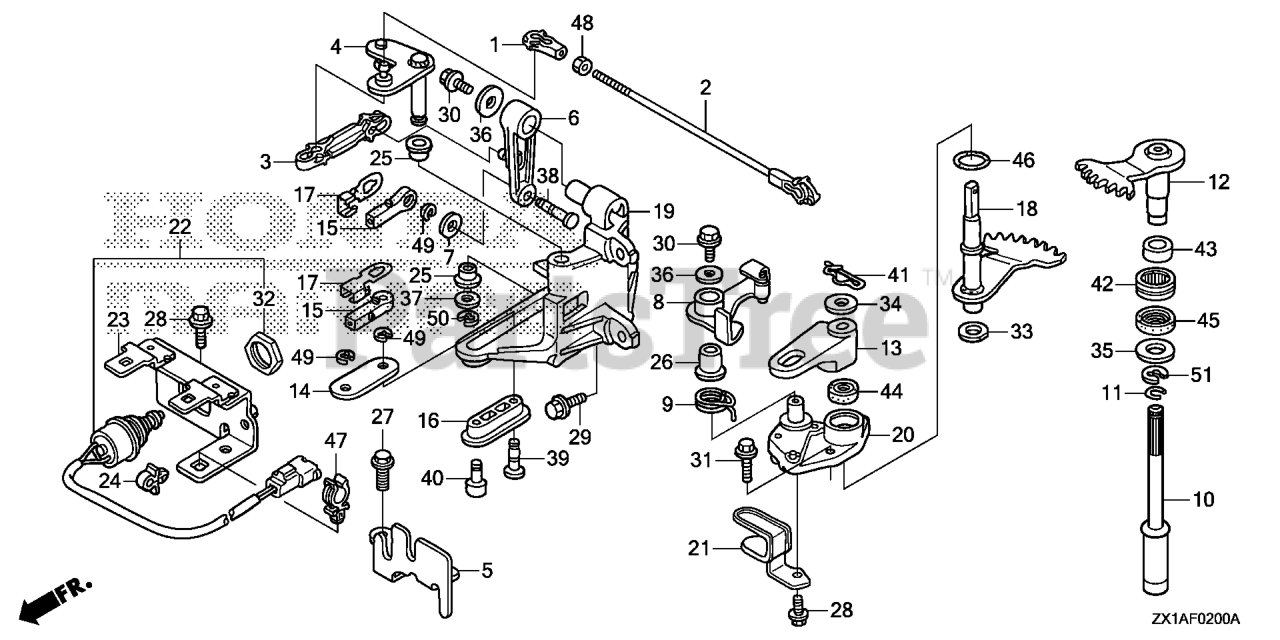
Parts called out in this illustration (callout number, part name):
1	LINKAGE, PIVOT
2	ROD, THROTTLE
3	LINK, THROTTLE
4	PLATE, THROTTLE
5	PLATE, REMOTE CONTROL CABLE
6	ARM, THROTTLE
7	WASHER, PIVOT
8	ARM, CLICK
9	SPRING, CLICK
10	ROD A, SHIFT (XL)
11	RING, STOPPER
12	SHAFT A, SHIFT
13	ARM, SHIFT
14	PLATE, SHIFT PIVOT
15	PIVOT, SHIFT
16	PIVOT, SHIFT SLIDE
17	PLATE, LOCK
18	SHAFT B, SHIFT
19	BRACKET, SHIFT LINK
20	HOLDER, SEAL *NH8* (DARK GRAY)
21	BRACKET A, CABLE
22	SWITCH ASSY., NEUTRAL
23	BRACKET, NEUTRAL SWITCH
24	CLIP, BRAKE PIPE (A) (FOR NEUTRAL SWITCH)
25	BUSH A, COVER LOCK
26	BUSH, BLADE BRAKE
27	BOLT, FLANGE (6X16)
28	BOLT, FLANGE (6X14)
29	BOLT, FLANGE (6X18)
30	BOLT, FLANGE (6X12) Use from Frame SN 1005249.
31	BOLT, FLANGE (6X20) (ENGINE NO.)
32	NUT, HEX. (20MM) Use up to Frame SN 1300359.
33	WASHER B, THRUST (14MM)
33	WASHER, SHIFT SHAFT
34	WASHER, PLAIN (12MM)
36	WASHER, PLAIN (6MM)
37	WASHER, PLAIN (8MM) Use from Frame SN 4800713.
39	PIN, SHIFT LINK
41	PIN, SNAP (12MM)
42	BEARING, NEEDLE (20X28X13) (SOLID)
43	RING (INNER) (15X20X13)
44	OIL SEAL (14X26X6)
45	SEAL, WATER (14X26X8)
46	O-RING (25X2.4) (NOK)
47	HOLDER, DRAIN TUBE
48	NUT, HEX. (5MM)
49	E-RING (4MM)
50	E-RING (6MM)
51	E-RING (12MM)
